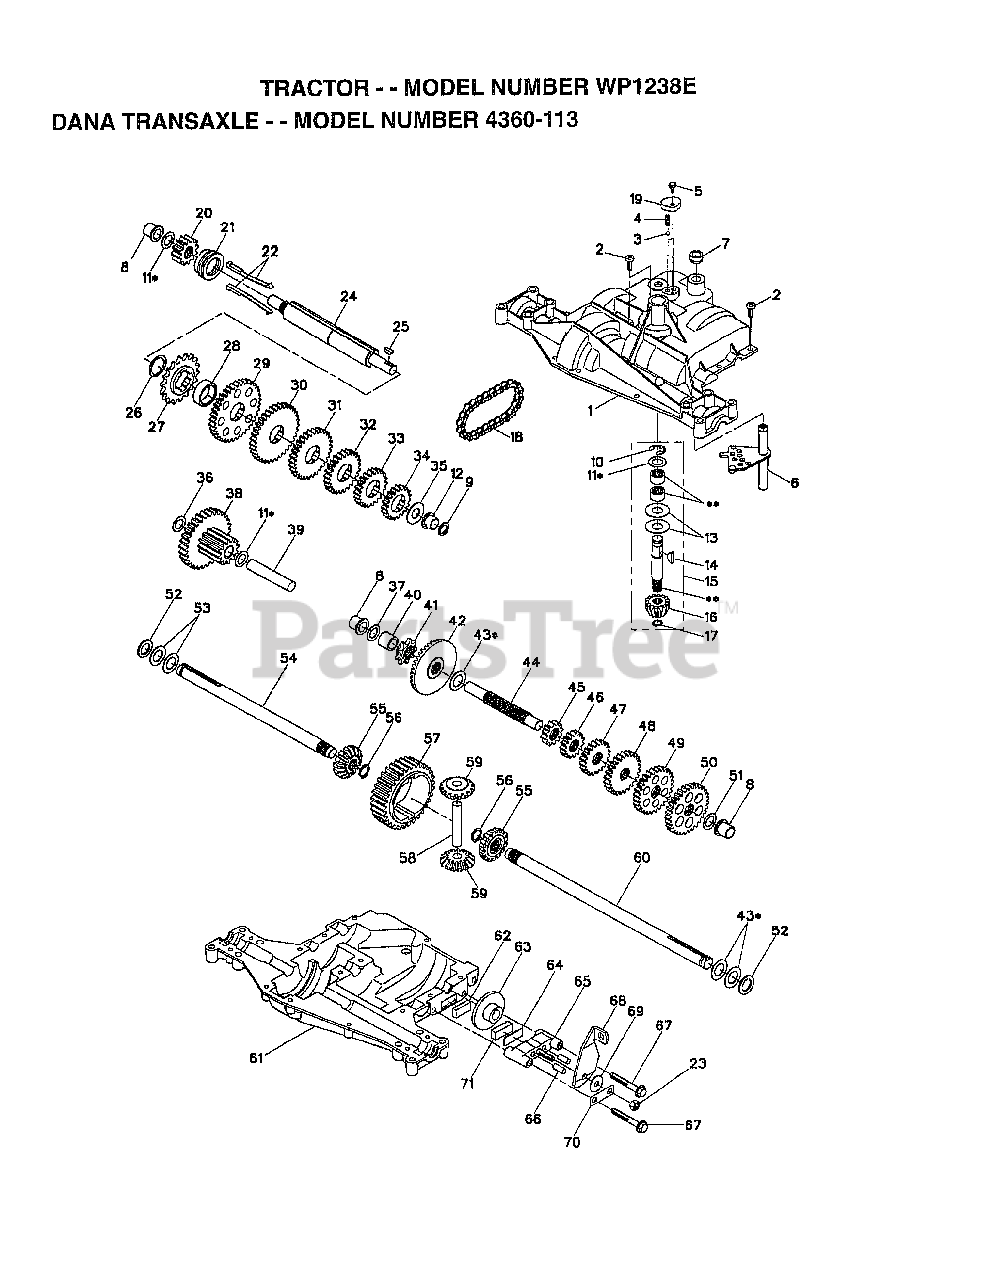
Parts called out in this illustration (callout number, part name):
1	HOUSING.UPPER.DANA.(5305J)
4	"SPRING, DETENT LT"
5	SCREW.TAPPING.1/4-20X.734
6	KIT SHIFTER ASM
9	SEAL.OIL.DAN.5508
10	RETAINING RING LT
11	ASM KIT SHIM 4689
12	BEARING.FLNG.5511
13	WASHER T
14	KEY WOODRUFF-DANA
15	AS KIT INPUT SHFT
16	PINION 14T T
17	"RING,RETAINING LT"
18	"CHAIN,24 PTCH LT"
19	COVER.DETENT.(5584)
20	GEAR.SPUR.12T.(5627)
21	CLUTCH.COL.5467
22	ASM KIT CLTCH KEY
23	NUT.LOCK.5/16-24
24	SHAFT INTERM DANA
25	WOODRUFF KEY
26	"RING,RETAINING LT"
27	SPROCKET 18T T
28	SPACER YT
29	GEAR SPUR 37 TTH
30	GEAR SPUR 35 TTH
31	GEAR SPUR 30T
32	GEAR 25T LT
33	GEAR SPUR 22 TT
34	SPUR GEAR 19T
35	"WASHER, PLAIN LT"
36	WASHER 045
37	WASHER 031
38	ASSY.GEAR.6153 12T&30T
39	SHAFT IDLER
40	SPACER T
41	SPROCKET 9T LT
43	ASM KIT SHIM
44	SHAFT T
45	GEAR SPUR 12 TTH
47	GEAR SPUR 20T
48	"GEAR, SPUR 25T LT"
49	GEAR 28T T
50	"GEAR, SPUR 31T LT"
51	WASHER 060
52	NEOPRENE WASHER
53	WASHER 031
54	AXLE.LH(5528-1)
55	GEAR 15T T
56	RING.RETAINING.(5270)
58	SHAFT T
59	GEAR 1ST T
60	AXLE.RH.(5528-2) DANA
61	HOUSING LOWER TNS
62	PUCK T
63	BRAKE DISC. T
64	SPACER LT
66	PIN T
67	SCREW.(5562) .5/16-18X2.35
69	WASHER LT
70	BRACKET, ANTI-ROTATION
71	PUCK T
